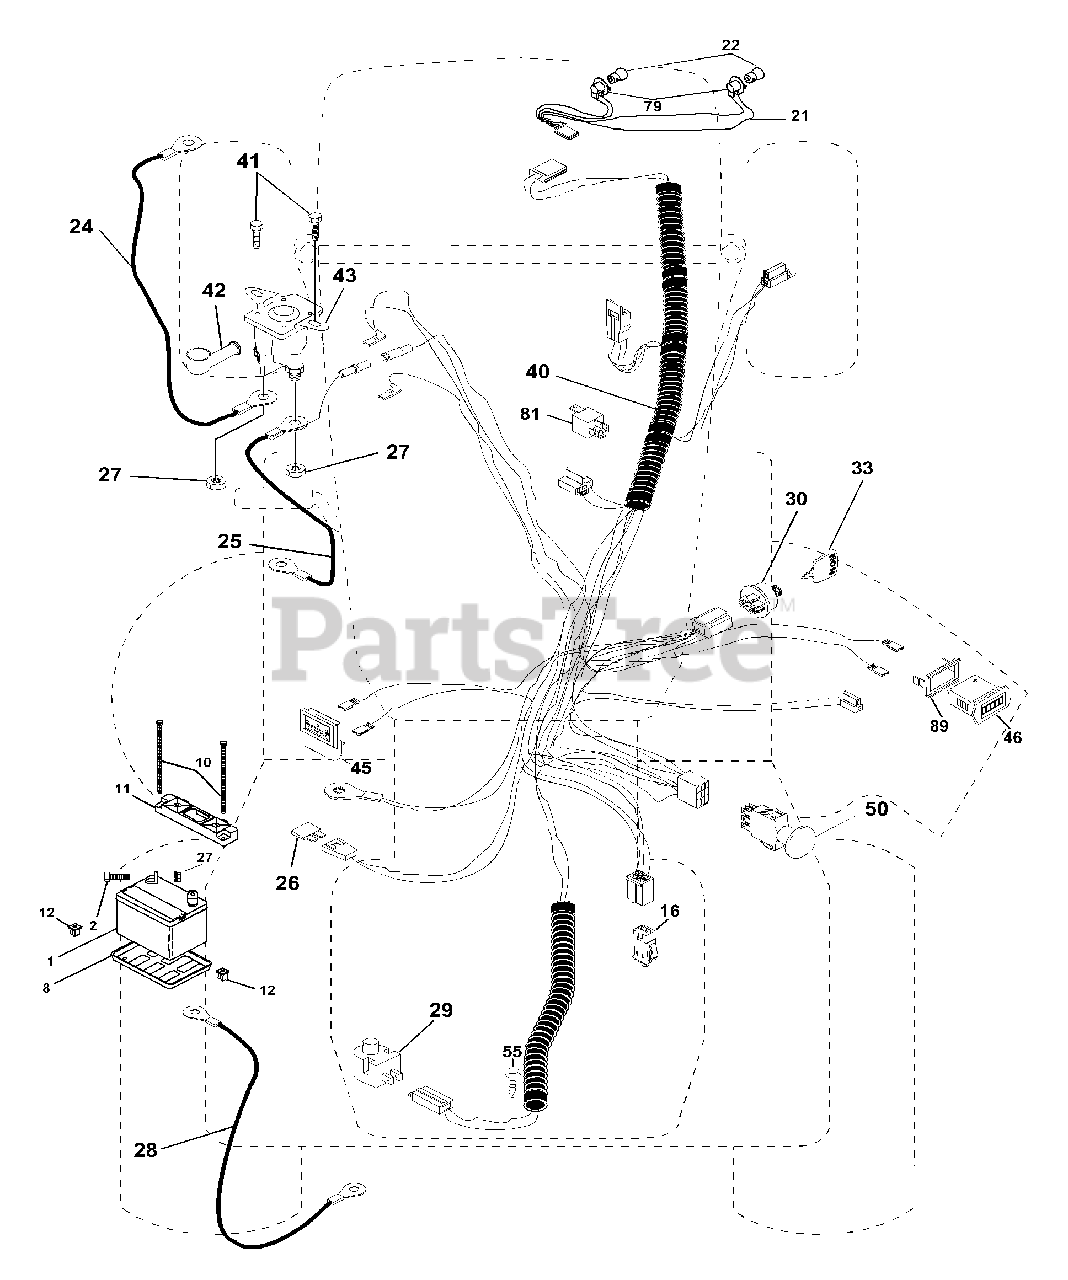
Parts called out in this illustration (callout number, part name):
1	Battery
2	Bolt Hex Head 1/4-20 x 3/4
8	Tray, Battery
10	Bolt Btr Frt 1/4-20 X 7.5 zinc
11	Holdown Battery Front Mount
12	Nut Push Nylon 1/4"
16	Switch Interlock Push-In
21	Harness Headlight w/Bulbs
22	Bulb Light
24	Cable, Battery
25	Cable, Battery
26	Fuse
27	Nut Keps Hex 1/4-20 Unc
28	Cable, Ground
29	Switch, Plunger
30	Switch, Ign
33	Key
40	Harness, Ignition
41	Screw 1/4-20 x 1/2
42	Cover, Terminal Red
43	Solenoid
45	Ammeter
46	Hourmeter Snap-In
50	Switch, PTO
79	Socket, Light Bulb
81	Relay Asm.
89	Bracket Snap-In
